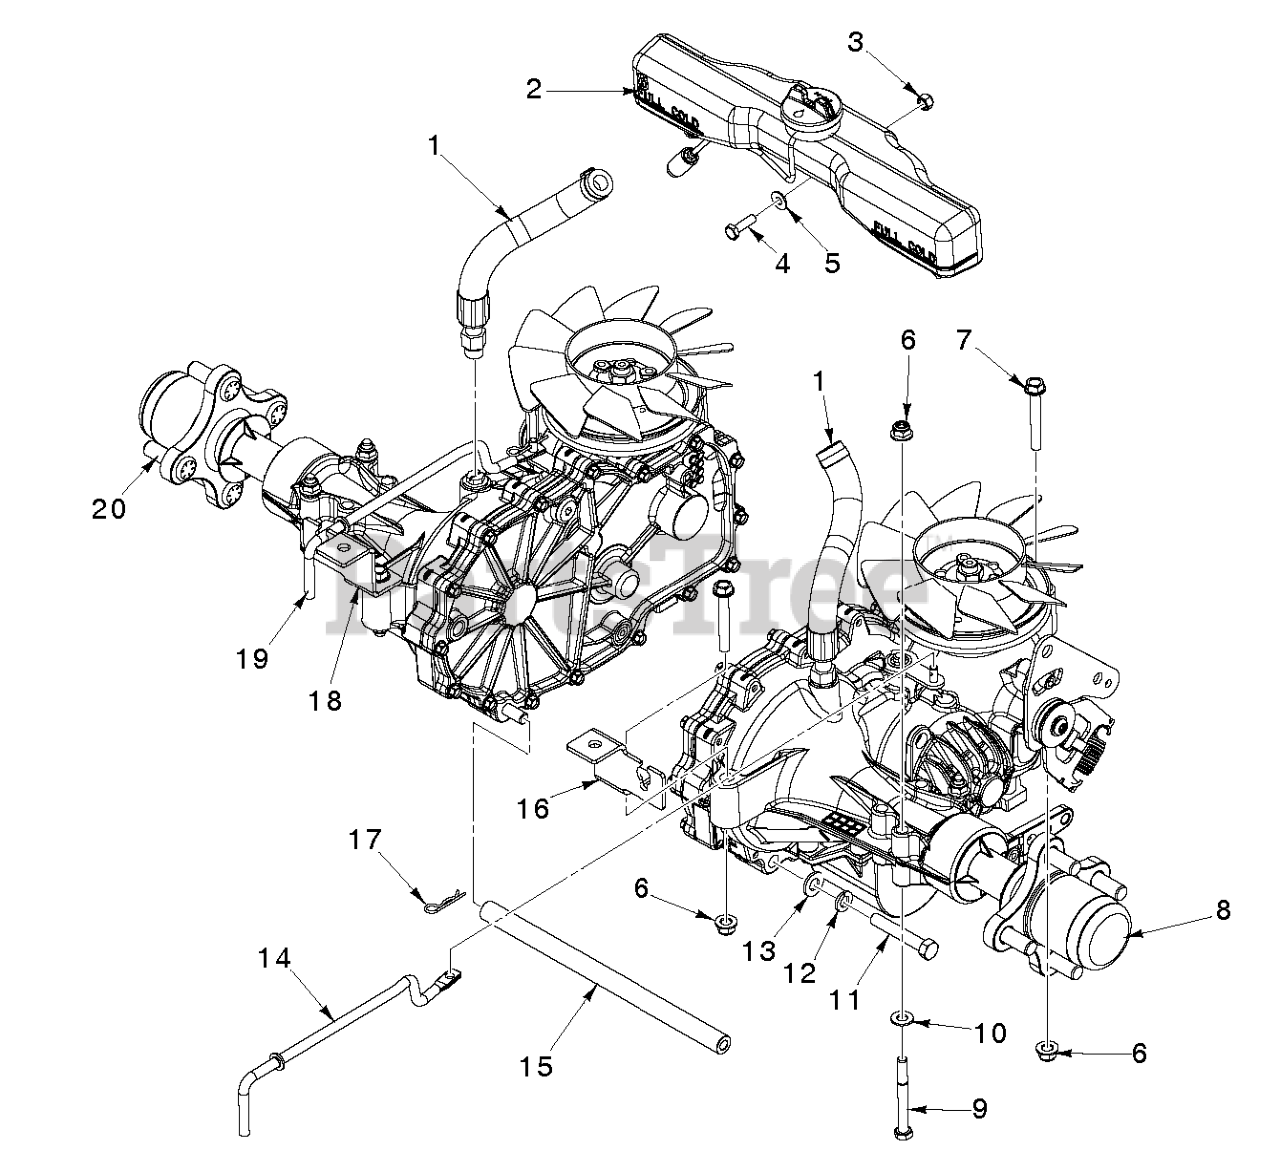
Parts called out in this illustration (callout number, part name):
1	HOSE ASSY, EXPANSION
2	TANK EXPANSION W/CAP
3	NUT HEXAGON 1/4-20 ST ZPB
5	WASHER PLAIN WASHER 9/32 X 5/8
6	NUT HEXAGON FLANGE 5/16-18 ST
8	HG_TRANS ZT-3100 RT
10	WASHER 11/32 X 11/16 X 14 GA T
13	WASHER PLAIN WASHER 3/8 X 0.08
16	BRACKET TRANS, RT BLACK MS-431
18	BRACKET TRANS, LT BLACK MS-431
20	HG_TRANS ZT-3100 LT
